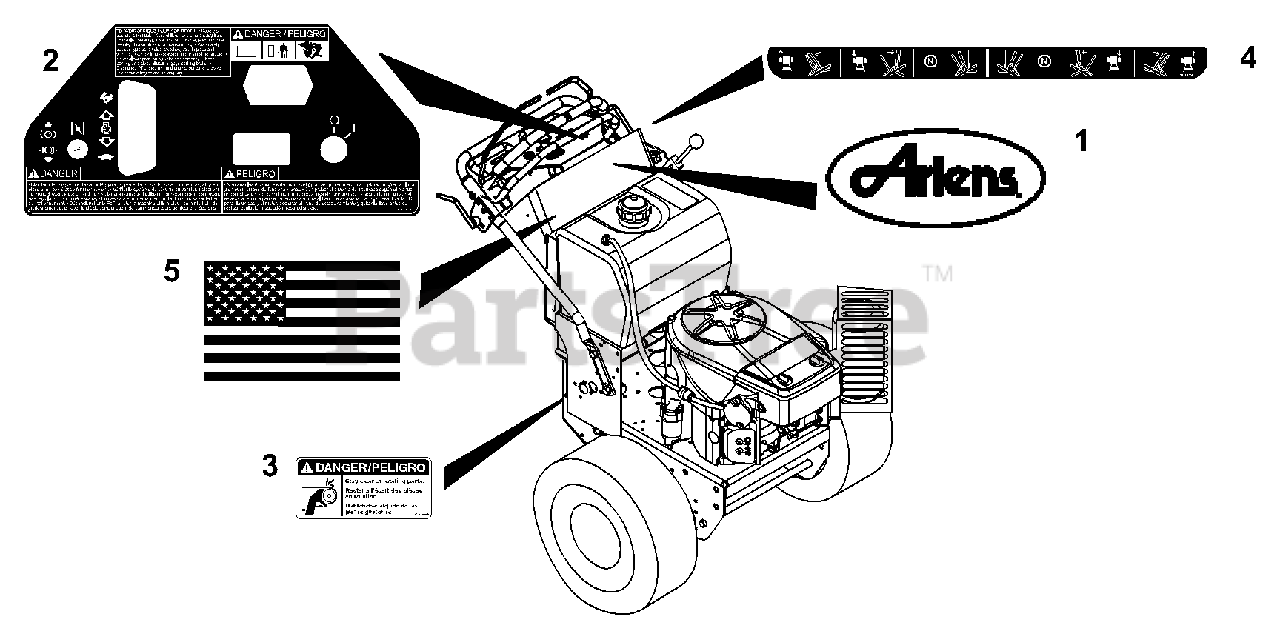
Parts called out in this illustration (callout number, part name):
1	DECAL, ARIENS
2	DECAL - CONTROL HR15 - ERGO
3	DECAL-DANGER-BELT ROTATING
4	DECAL-STEER LEVERS-HYDRO-ERGO
5	DECAL, AMERICAN FLAG
